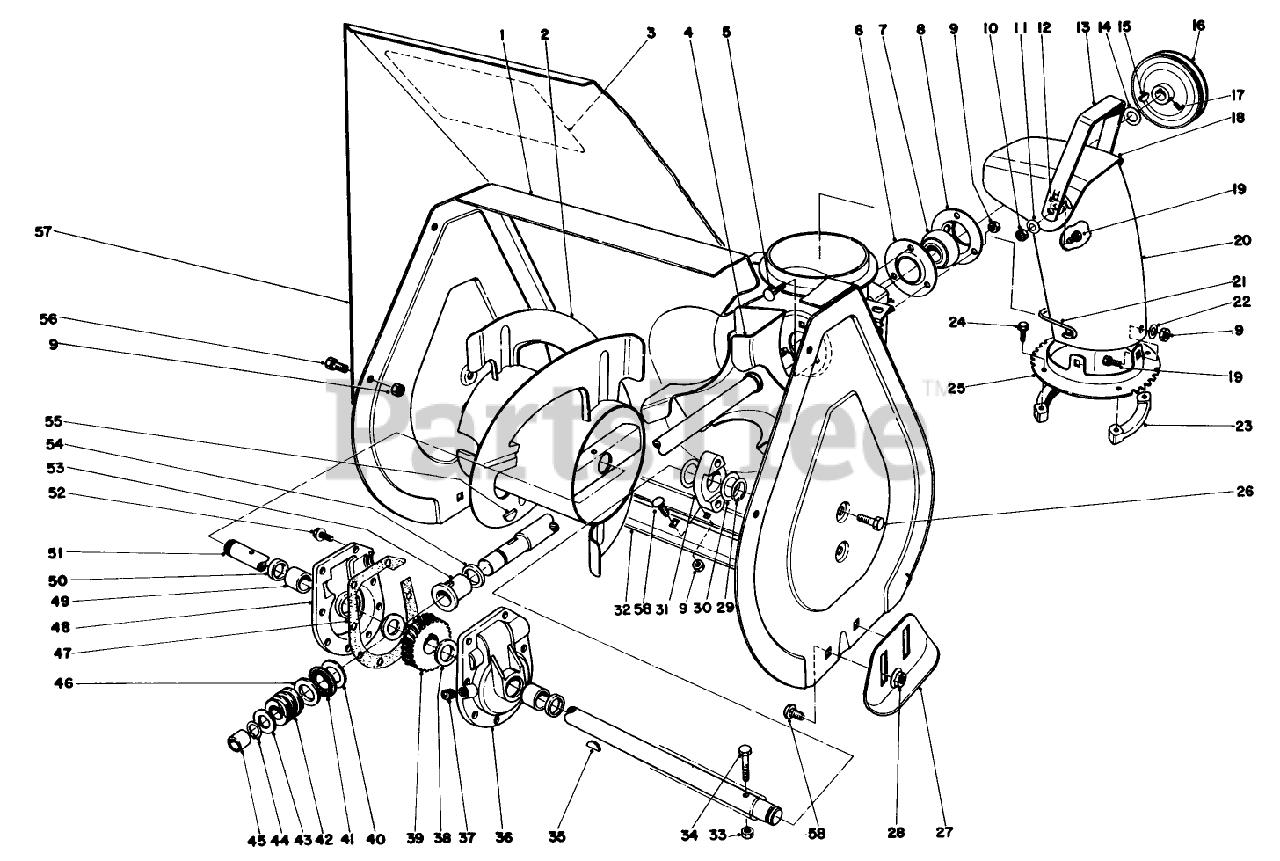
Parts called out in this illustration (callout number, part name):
1	Auger Housing
2	Auger R.H.
3	Decal
4	Shaft & Impeiler
5	BOLT-CARR
6	FLANGE-CUP, BEARING
7	Ball Bearing
8	FLANGE-CUP, BEARING
9	NUT-LOCK, NI
10	NUT-LOCK, CONE
11	WASHER-BELLEVILLE
12	WASHER-RUBBER
13	Handle Deflector
14	WASHER
15	KEY-WOODRUFF
16	PULLEY
17	SCREW-SET, SQH
18	Deflector
19	SCREW-HH
20	Chute-Discharge
21	Chute Guard
22	WASHER-PLAIN
23	RING-CHUTE, RETAINER
24	SCREW-SPECIAL
25	Chute Ring
26	SCREW-HWHTF
27	Skid
28	NUT-HF
29	RING-RETAINING
30	WASHER
31	BEARING-AUGER
32	Blade-Scraper
33	NUT-LOCK, CONE
34	SCREW-HH
35	KEY-WOODRUFF
36	Gear Case L.H. (Incl. Ref. #49 & 50)
37	PLUG-PIPE, SQH
38	WASHER-THRUST
39	Gear
40	WASHER-THRUST
41	BEARING-THRUST
43	WASHER-THRUST
44	Ring-Snap
45	BUSHING
46	WASHER-THRUST
47	asket
48	Gear Case R.H. (Incl. Ref. #49 & 50)
49	BUSHING
50	SEAL-OIL
51	AUGER SHAFT
52	SCREW-TAPTITE
53	BUSHING-INPUT
54	RING-QUAD
55	KEY-WOODRUFF
56	SCREW-HH
57	AUGER EXT 21 SCAND
58	BOLT-CARR
